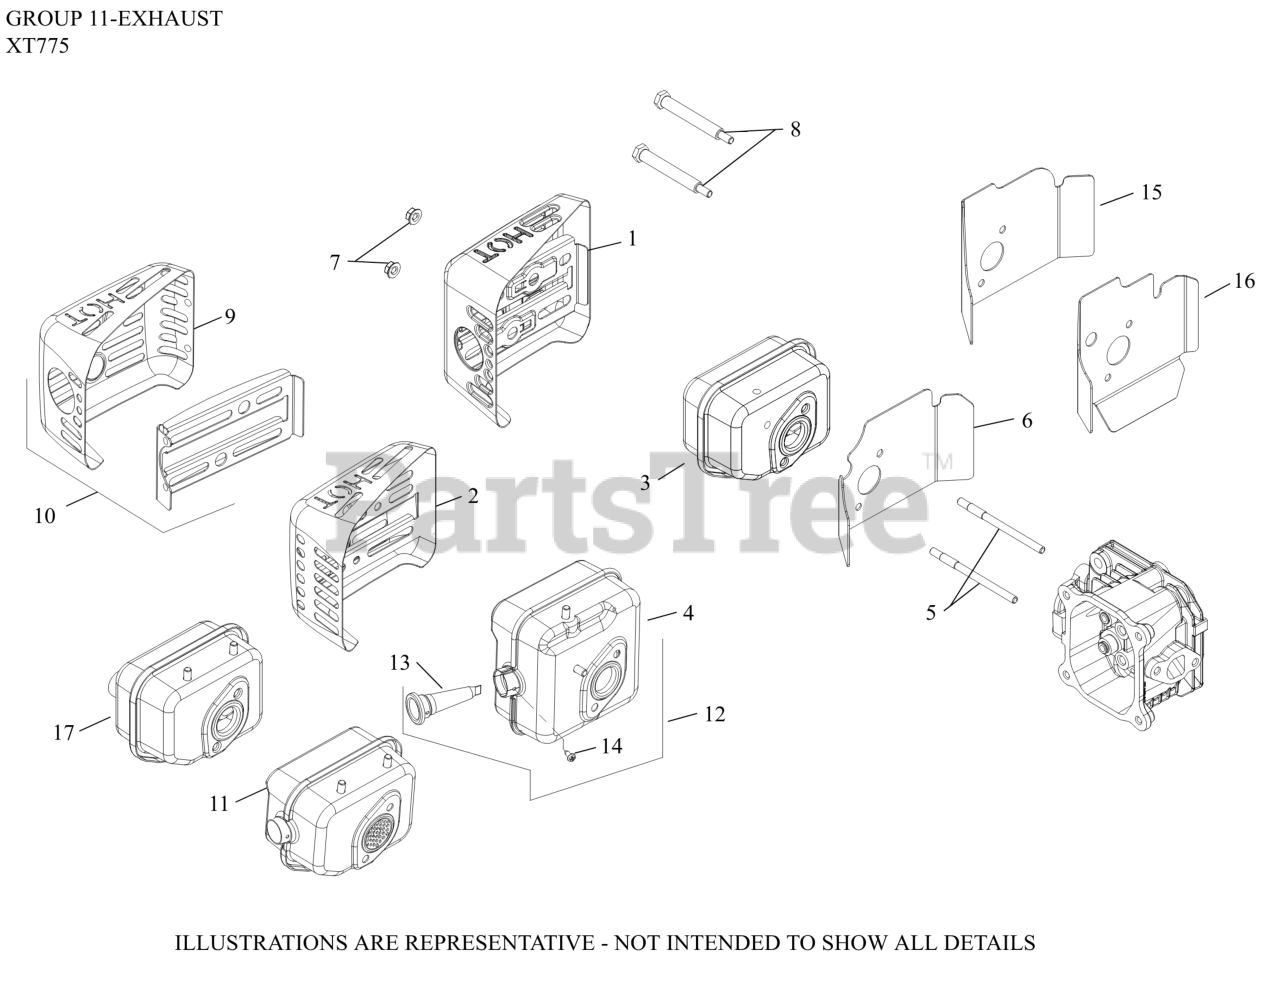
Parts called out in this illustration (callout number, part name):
2	GUARD, MUFFLER
3	KIT, MUFFLER
5	STUD (M6)
7	NUT, HEX FLANGE LOCK (M6)
15	GASKET, MUFFLER (HEAT DEFLECTOR)
